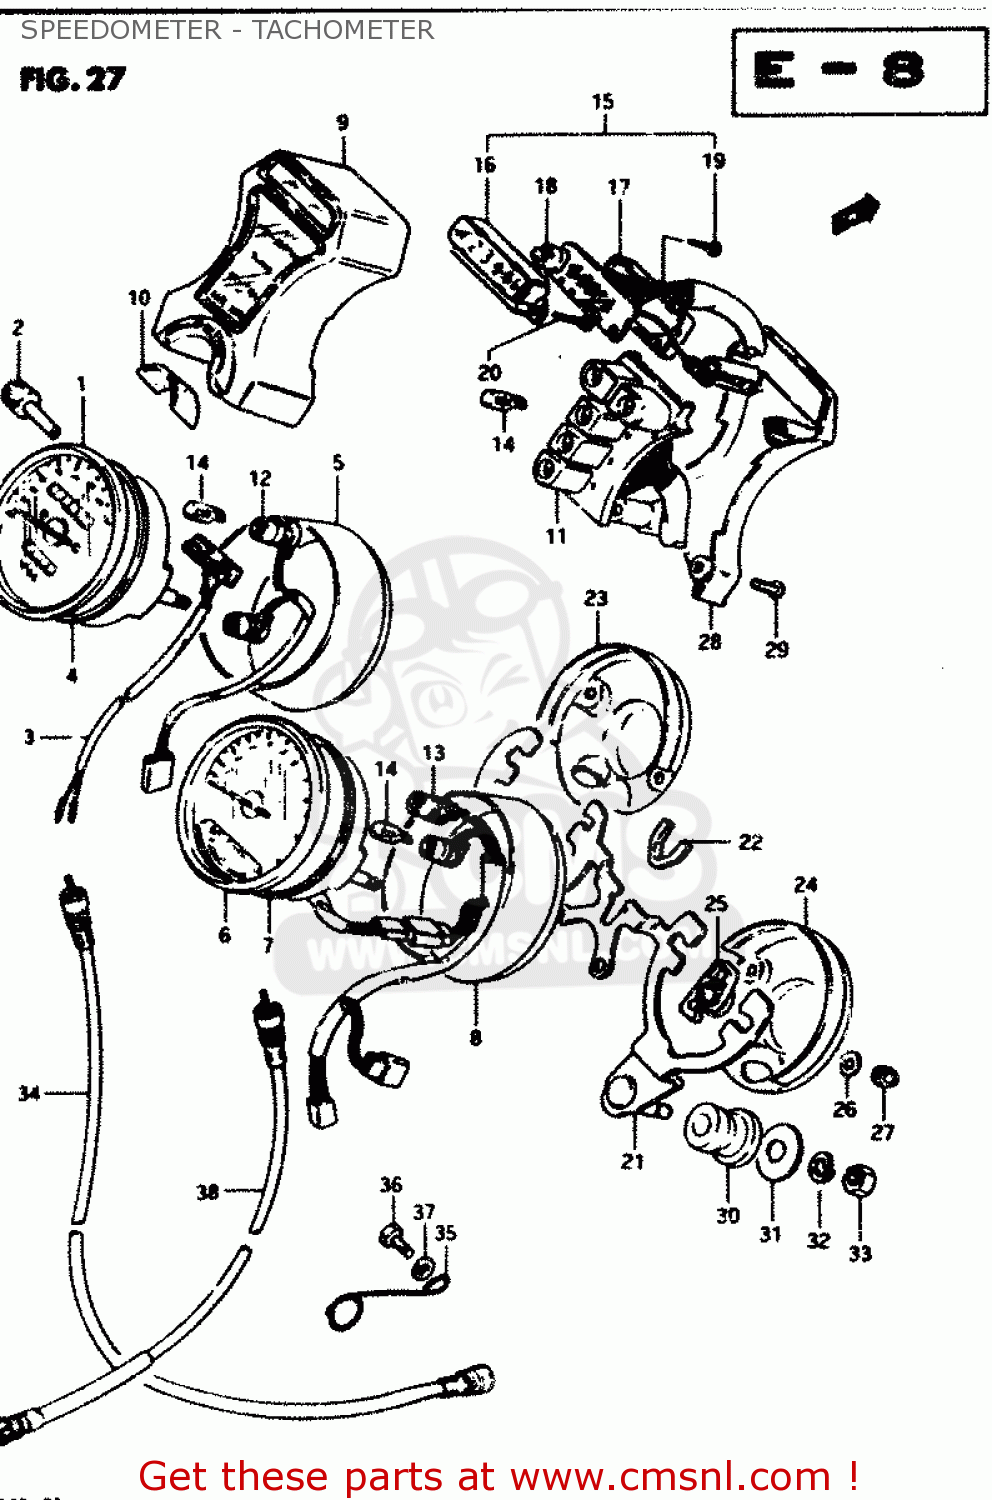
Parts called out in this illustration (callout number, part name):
1	SPEEDOMETER (KILO)
2	KNOB,TRIP
3	WIRE,LEAD
4	CUSHION,METER
5	COVER,SPEEDOMETER
6	METER,TACHOMETER
7	CUSHION,METER
8	COVER,TACHOMETER
9	CASE,PILOT BOX
10	SEAL,IGNITION SWITCH
11	SOCKET,PILOT BOX
12	SOCKET,SPEEDOMETER
13	SOCKET,TACHOMETER
14	BULB(12V3.4W,T10)
15	INDICATOR, GEAR POSITION
16	CASE,GEAR INDICATOR
17	COVER,LWR
18	BULB(14V1.12W)
19	SCREW,GEAR INDICATOR
20	SCREW
21	BRACKET,COMBINATION METER
22	BRACKET,COVER
23	COVER,METER,UNDER
24	COVER,TACHOMETER,UNDER
25	CUSHION
26	WASHER
27	NUT
28	COVER,PILOT BOX LWR
29	SCREW,PILOT BULB CASE
30	CUSHION,METER BRACKET
31	WASHER (8.5X29X1.6)
32	LOCK WASHER
33	NUT
34	CABLE ASSEMBLY,SPEEDOMETER
35	CLAMP,SPEEDOMETER CABLE
36	BOLT, UPPER
37	WASHER
38	CABLE ASSEMBLY,TACHOMETER
